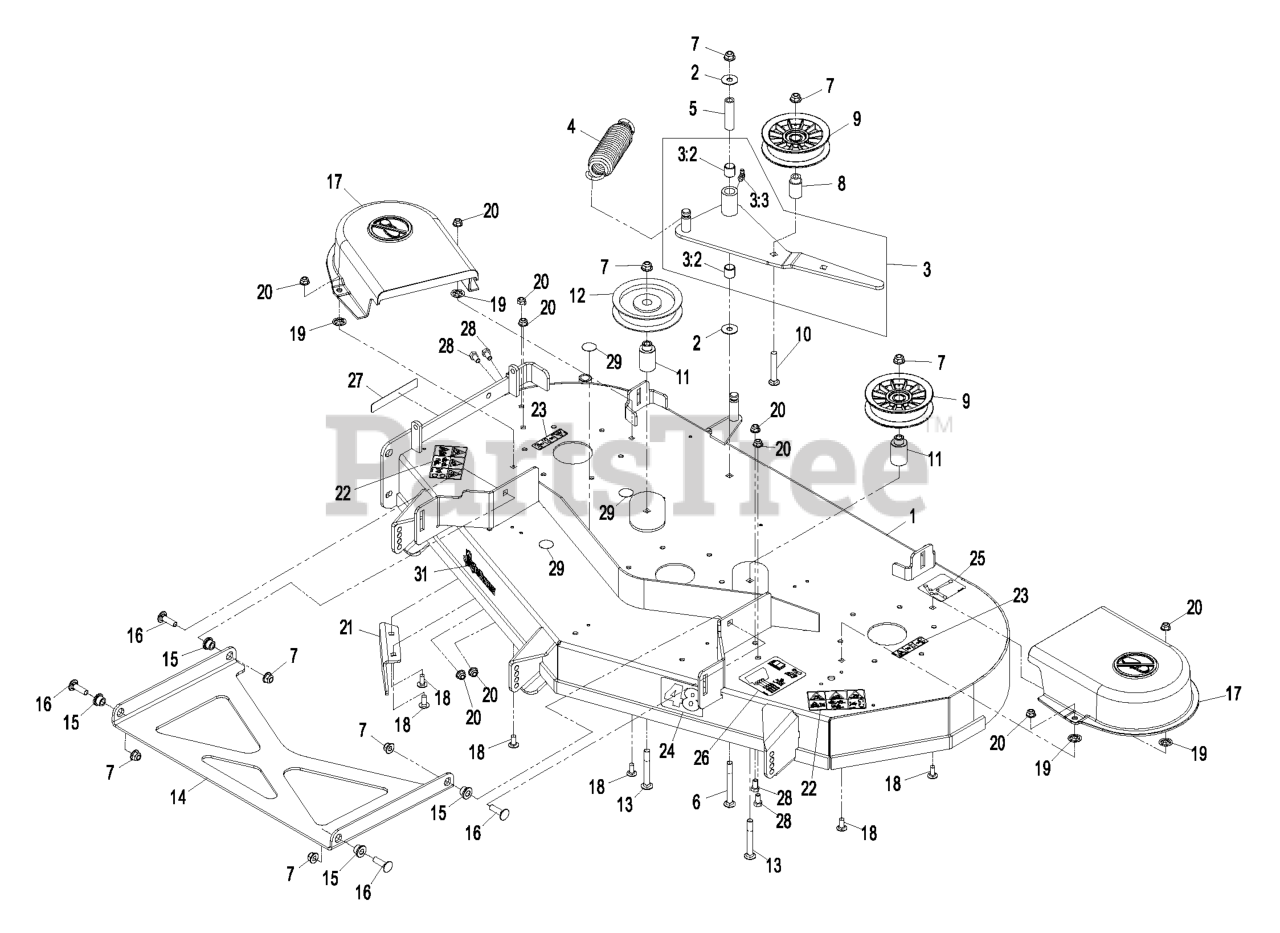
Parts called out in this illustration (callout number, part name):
1	48 INCH DECK ASM
3	IDLER ARM ASM
3:2	SLEEVE-BEARING
3:3	FITTING-GREASE, 90 DEG
4	SPRING, EXTENSION
5	BUSHING-PIVOT, IDLER
6	SCREW-CARR
7	NUT-HF, NI
8	BUSHING-IDLER
10	SCREW-CARR
11	BUSHING-IDLER
13	BOLT-CARRIAGE
14	STRUT-DECK
15	SPACER-STRUT
16	Bolt-Carriage 3/8-16 X 1 1/4
17	SHIELD-BELT
18	SCREW-CARR
19	RING-RETAINING
20	NUT-HF, NI
21	BAFFLE-DISCHARGE
22	DECAL-DANGER
23	DECAL-WARNING, BELT SHIEL
24	DECAL,DECK 48
25	DECAL-ROUTING, BELT
26	DECAL-ROLLER, ANTI-SCALP
27	DECAL-DANGER
28	SCREW-HH
31	Asm, 48 Deck Complete
